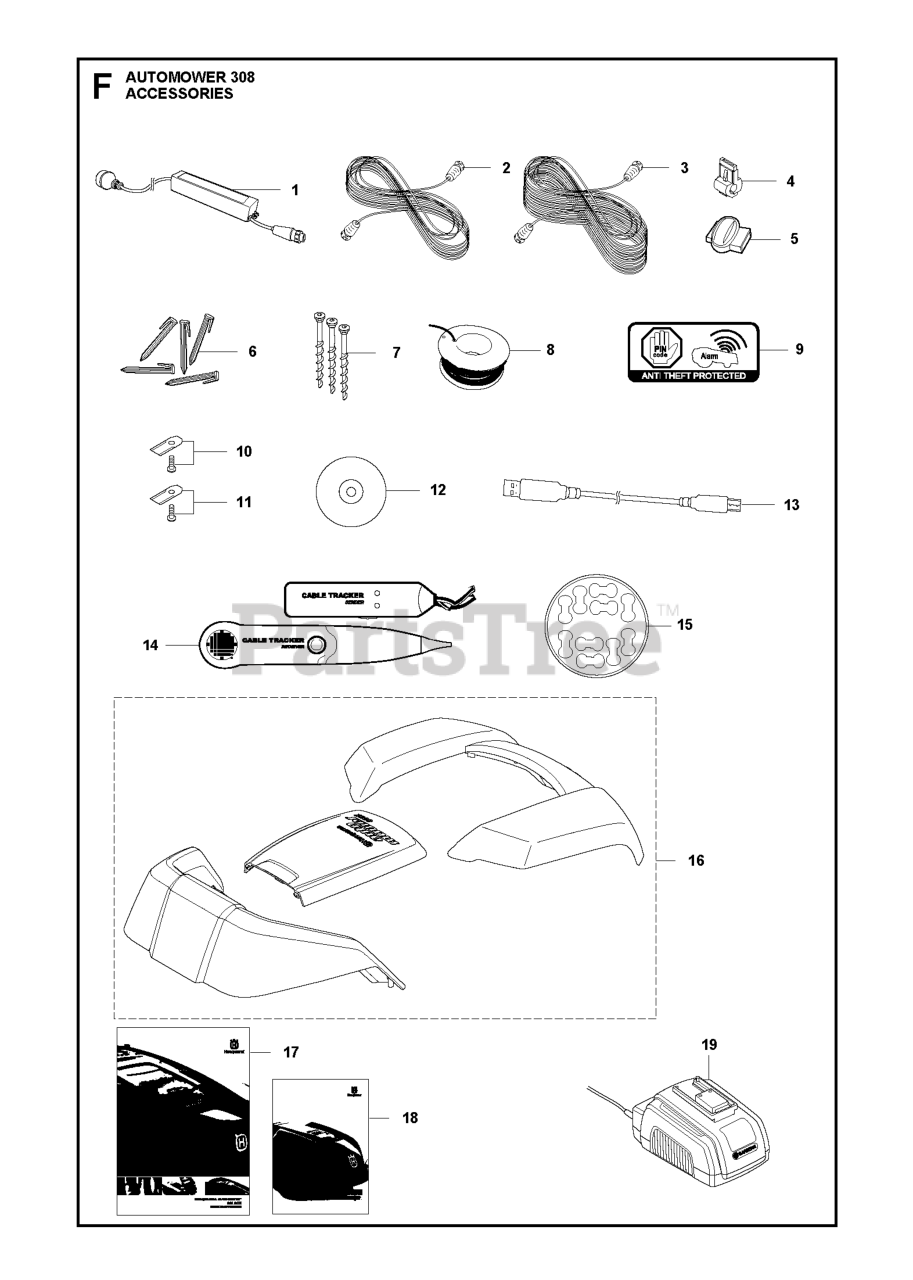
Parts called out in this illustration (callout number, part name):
4	BRAKER
4	CONNECTOR 5 PCS, BLISTER
5	SPLICE KIT
5	COUPLER SPLICER, 5 PCS,
5	SPLICE CONNECTOR 50 PCS/PK
6	STAPLE 100 PCS, BLISTER
6	STAPLES (100 CT BAG)
7	SCREW KIT KIT INCLUDES THREE S
7	SCREW 3 PCS, BLISTER PACK
8	LOOP WIRE 250M
8	LOOP WIRE 150M
8	WIRE 150M, BLISTER
10	BLADE KIT
10	BLADE
10	BLADE - 30 PCS
10	BLADE - BULK PACK 500 PCS
11	BLADE 300PCS -SINGLE HOLE THIC
11	BLADE CARBON STEEL, THICK BLAD
11	BLADE BLADE KIT INCL PACKAGING
11	BLADE 9PCS EXTRA THICK
14	TEST EQUIPMENT
